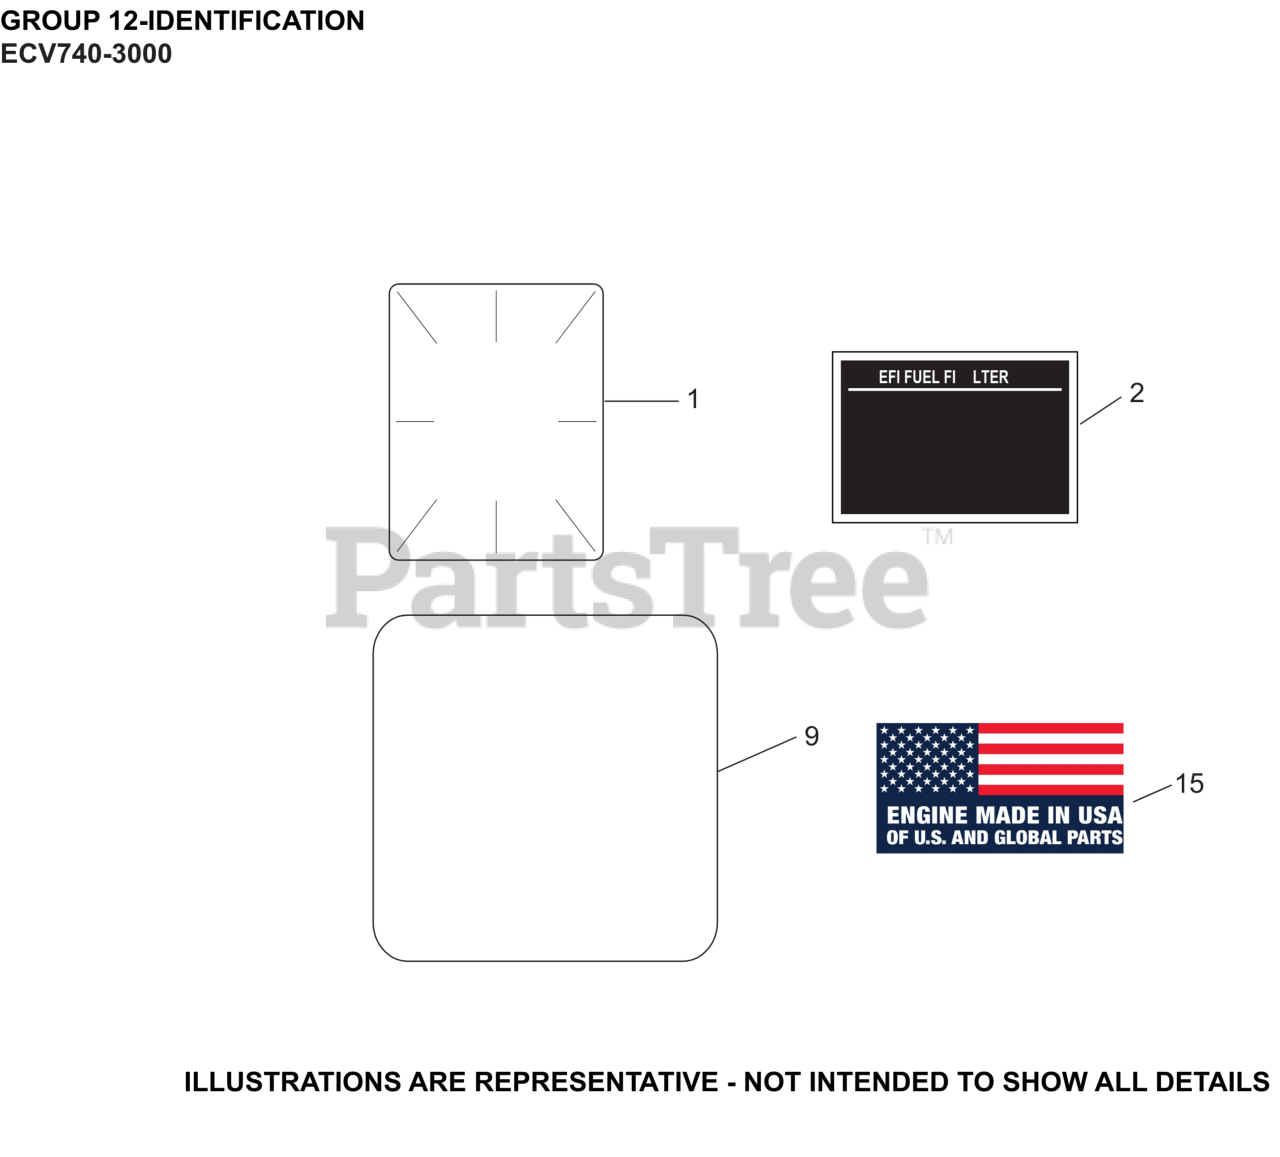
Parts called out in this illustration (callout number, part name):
1	LABEL, CLEAR LAMINATION
2	LABEL, EFI FUEL FILTER
9	DECAL HDAC, 25 HP/747cc/ECV-ECH740
15	DECAL, USA
